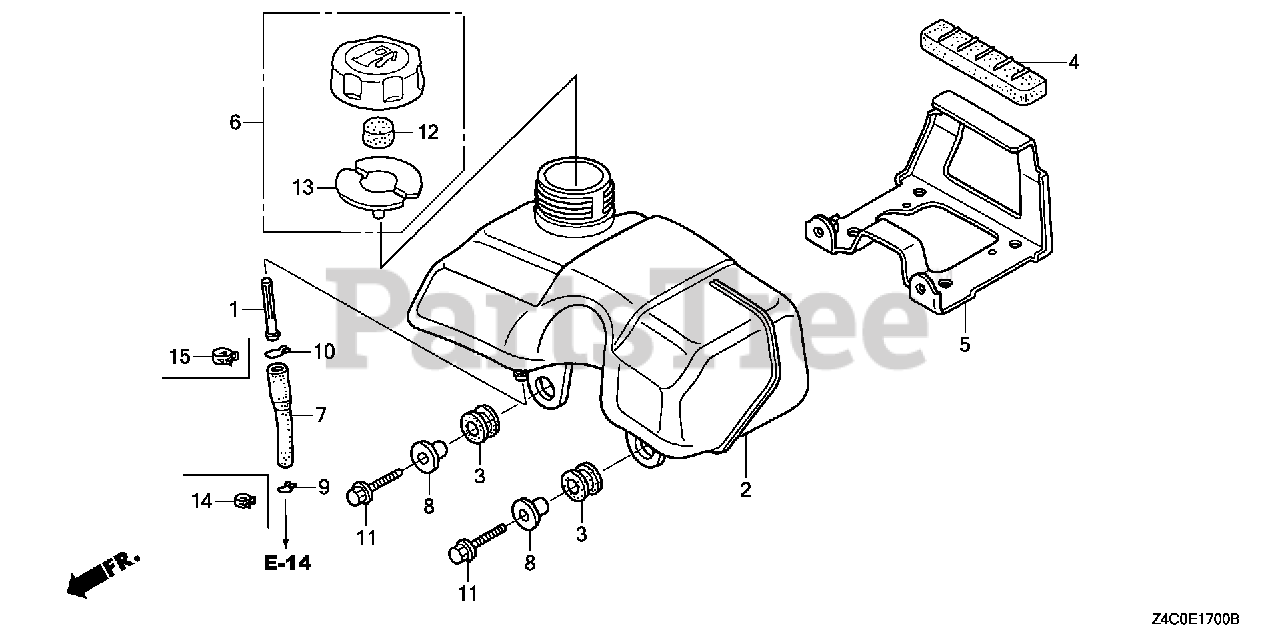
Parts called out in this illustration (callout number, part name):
1	FILTER, FUEL
2	TANK, FUEL
2	TANK, FUEL (FOR U.S.A.)
3	RUBBER A, TANK MOUNTING
4	RUBBER B, TANK MOUNTING
5	STAY, FUEL TANK
6	CAP ASSY., FUEL TANK
7	TUBE A, FUEL
7	TUBE A, FUEL (FKM)
8	COLLAR, CANISTER MOUNTING
9	CLIP, TUBE (B8)
10	CLIP, TUBE (B10)
11	BOLT, FLANGE (6X20)
12	SPONGE, FUEL CAP BREATHER
13	GASKET, FUEL CAP
14	CLAMP, TUBE (D8)
15	CLAMP, TUBE (D10.5)
